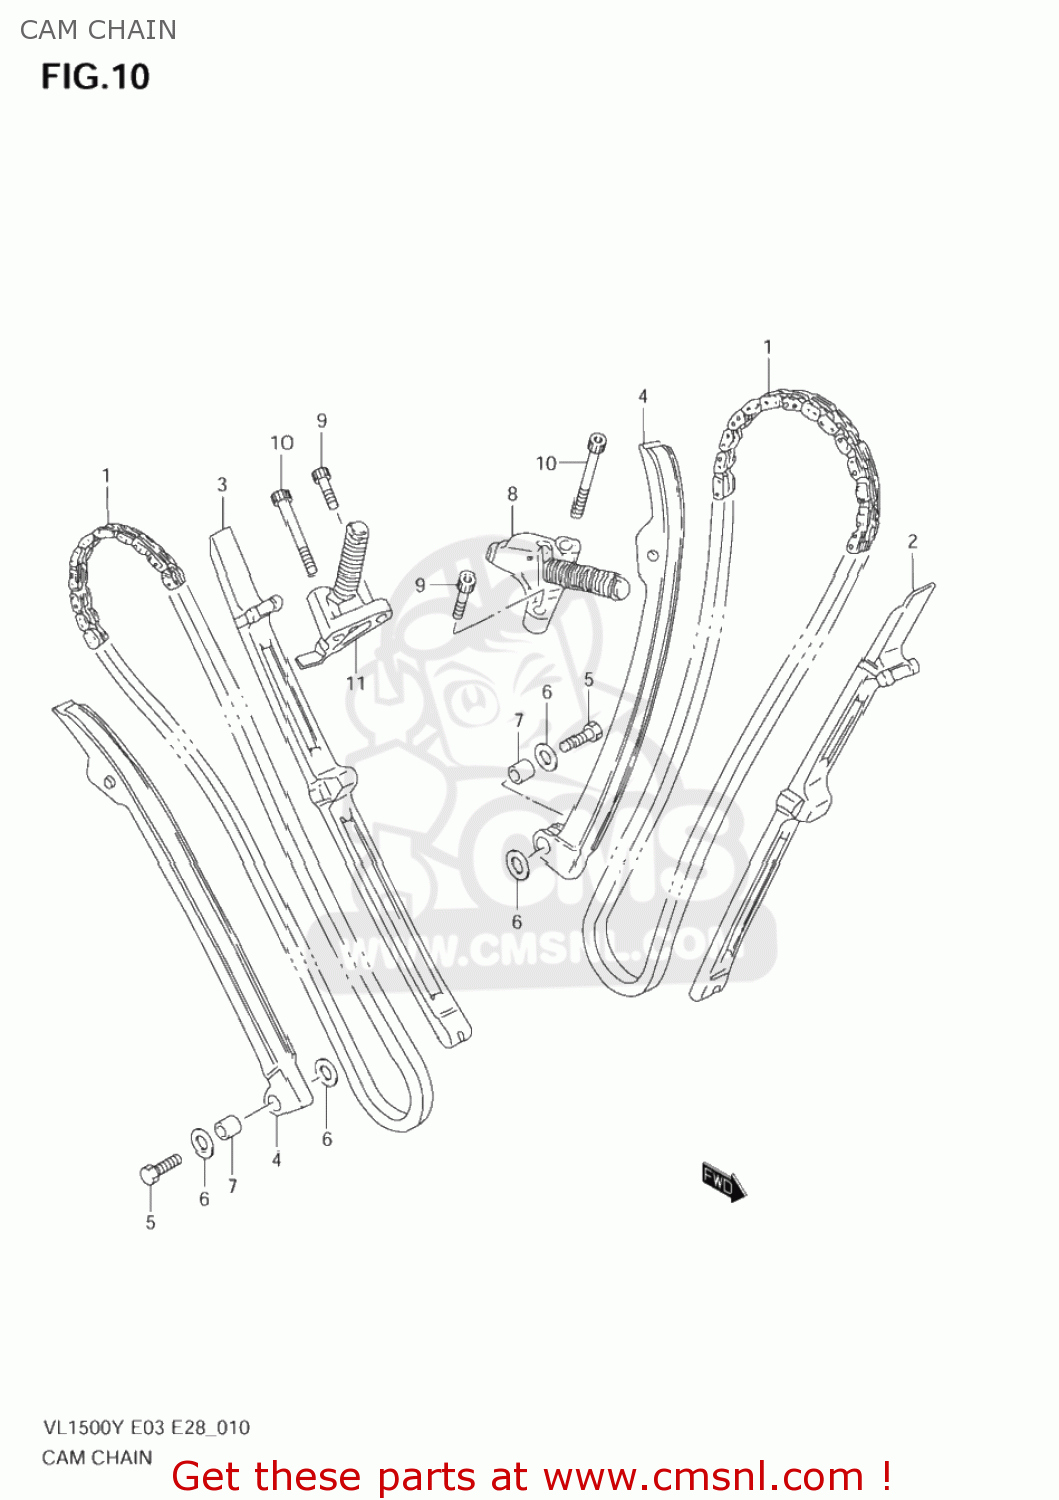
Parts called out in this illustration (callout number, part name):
1	CHAIN,CAMSHAFT DRIVE
2	GUIDE,CAM CHAIN
3	GUIDE,CAM CHAIN RR
4	TENSIONER,CAM CHAIN
5	BOLT(6X26)
6	WASHER
7	SPACER(6X11X9)
8	ADJUSTER ASSEMBLY,FRONT TENSIONER
9	BOLT,CRKCASE,R
10	BOLT
11	ADJUSTER ASSEMBLY,REAR TENSIONER
